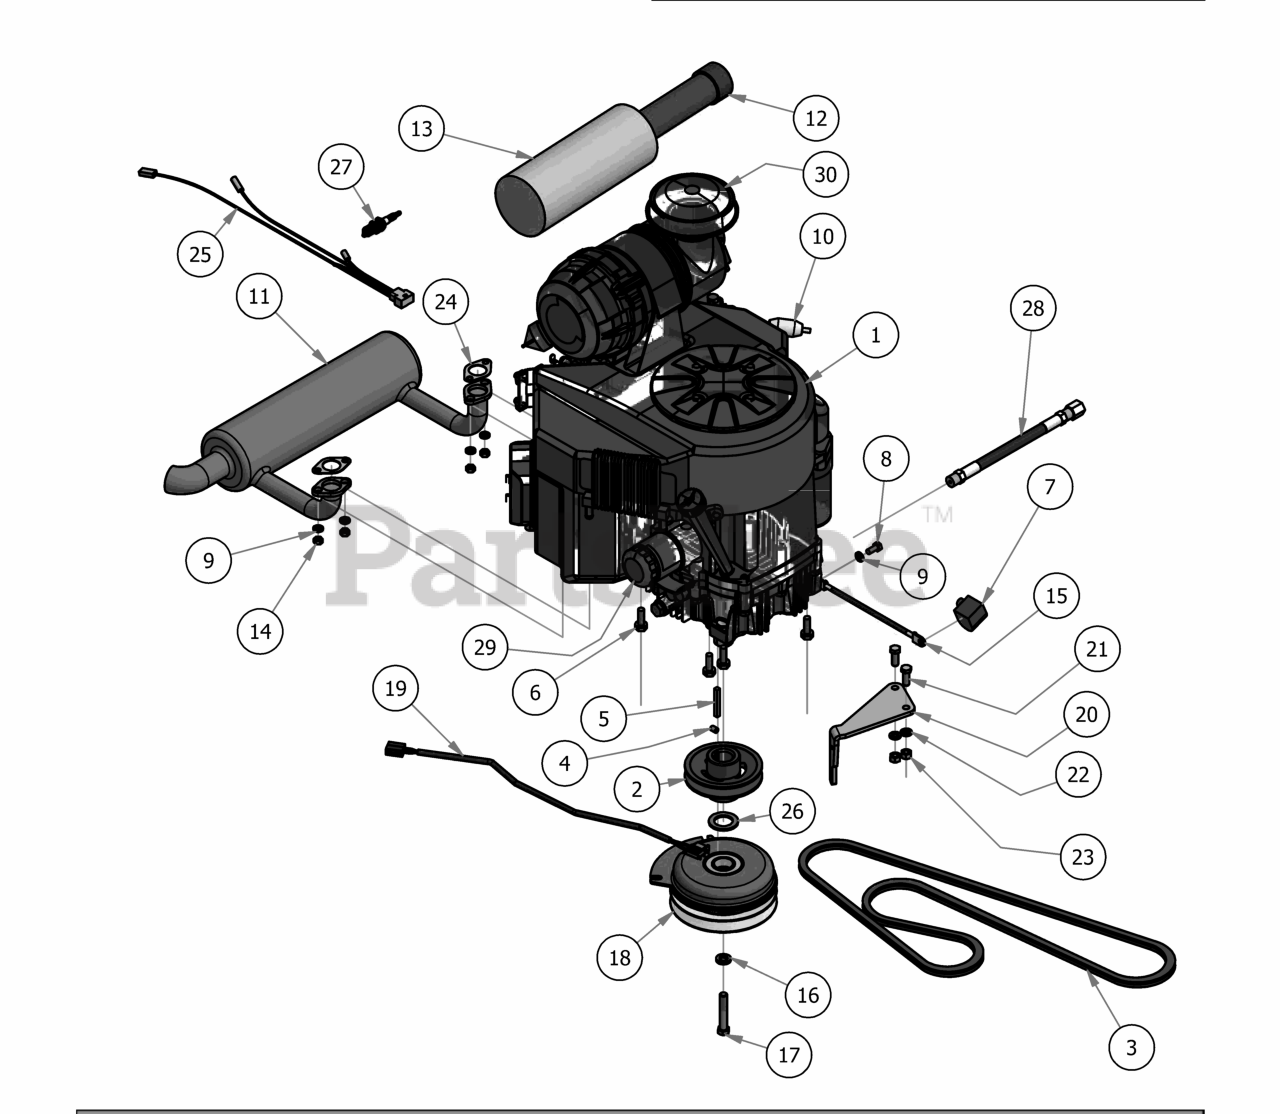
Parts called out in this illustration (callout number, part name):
1	Kawasaki Engine FX-850-V-CS09R
2	4 3/4 Motor Pulley
4	3/8" Set Screw
5	1/4 x 2 Square key Stock
6	3/8 x 1 1/8 bolt
7	Black Boot For Ground Cable
8	M8x1.20x20MM Hex head bolt
9	5/16" Lock Washer
10	Universal Inline Fuel Filter
11	Kawasaki Exhaust
12	Canister Air Filter- Inner
13	Canister Air Filter- Outer
14	M8-1.25 Zinc Nut
15	Ground Cable
16	7/16" Lock Washer
17	7/16" x 2 1/2" Hex Bolt
18	Clutch Assembly
19	Clutch Pigtail
20	PTO Engager Holder
21	3/8" x 1" Hex Bolt
22	3/8" Lock Washer
23	3/8" Hex Nut
24	Exhaust Gasket
25	Harness Adaptor
26	1 1/8" Flat Spacer
27	Spark Plug - Kawasaki
28	Oil drain Hose
29	Kawsaki Oil Filter
30	Kawasaki Rain Cap
